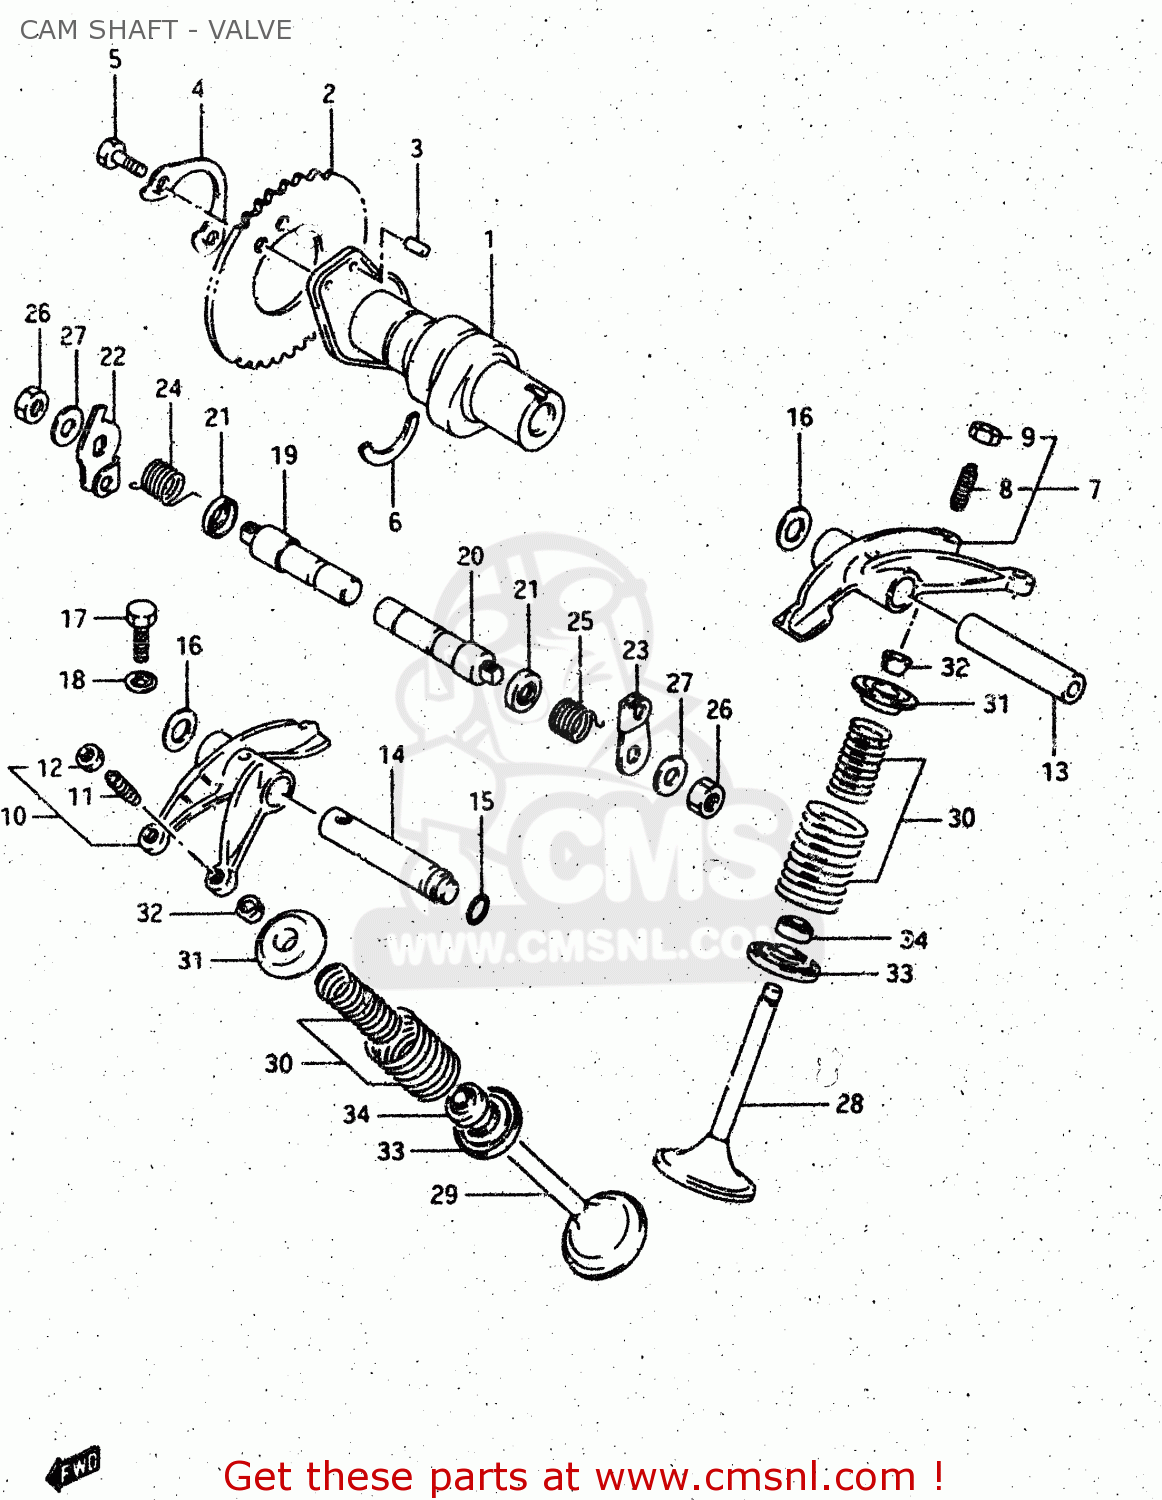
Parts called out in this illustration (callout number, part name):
1	CAMSHAFT
2	SPROCKET,CAMSHAFT(NT:42)
3	PIN
4	WASHER,CAM CHAIN SPROCKET
5	BOLT(6X12.5)
6	C RING
7	ARM,VALVE ROCKER,INTAKE
8	SCREW,TAPPET ADJUSTING
9	NUT,ADJUSTING SCREW
10	ARM,VALVE ROCKER EXHAUST
11	SCREW,TAPPET ADJUSTING
12	NUT,ADJUSTING SCREW
13	SHAFT,VALVE ROCKER ARM
14	SHAFT,EXHAUST VALVE ROCKER ARM
15	O RING(D:1.9,ID:8.6)
16	WASHER
17	BOLT 6X30
18	GASKET(5.8X13X1.2) (NAS)
19	SHAFT,DECOMP LH
20	SHAFT,DECOMP,L
21	OIL SEAL
22	LEVER,DECOMP SHAFT
23	LEVER,DECOMPRESSION SHAFT,LEFT
24	SPRING
25	SPRING
26	NUT 8MM
27	WASHER
28	VALVE,INTAKE
29	VALVE,EXHAUST
30	SPRING SET,VALVE
31	RETAINER,VALVE SPRING
32	COTTER VALVE
33	SEAT,VALVE SPRING
34	SEAL,OIL(7X14.4X9)
